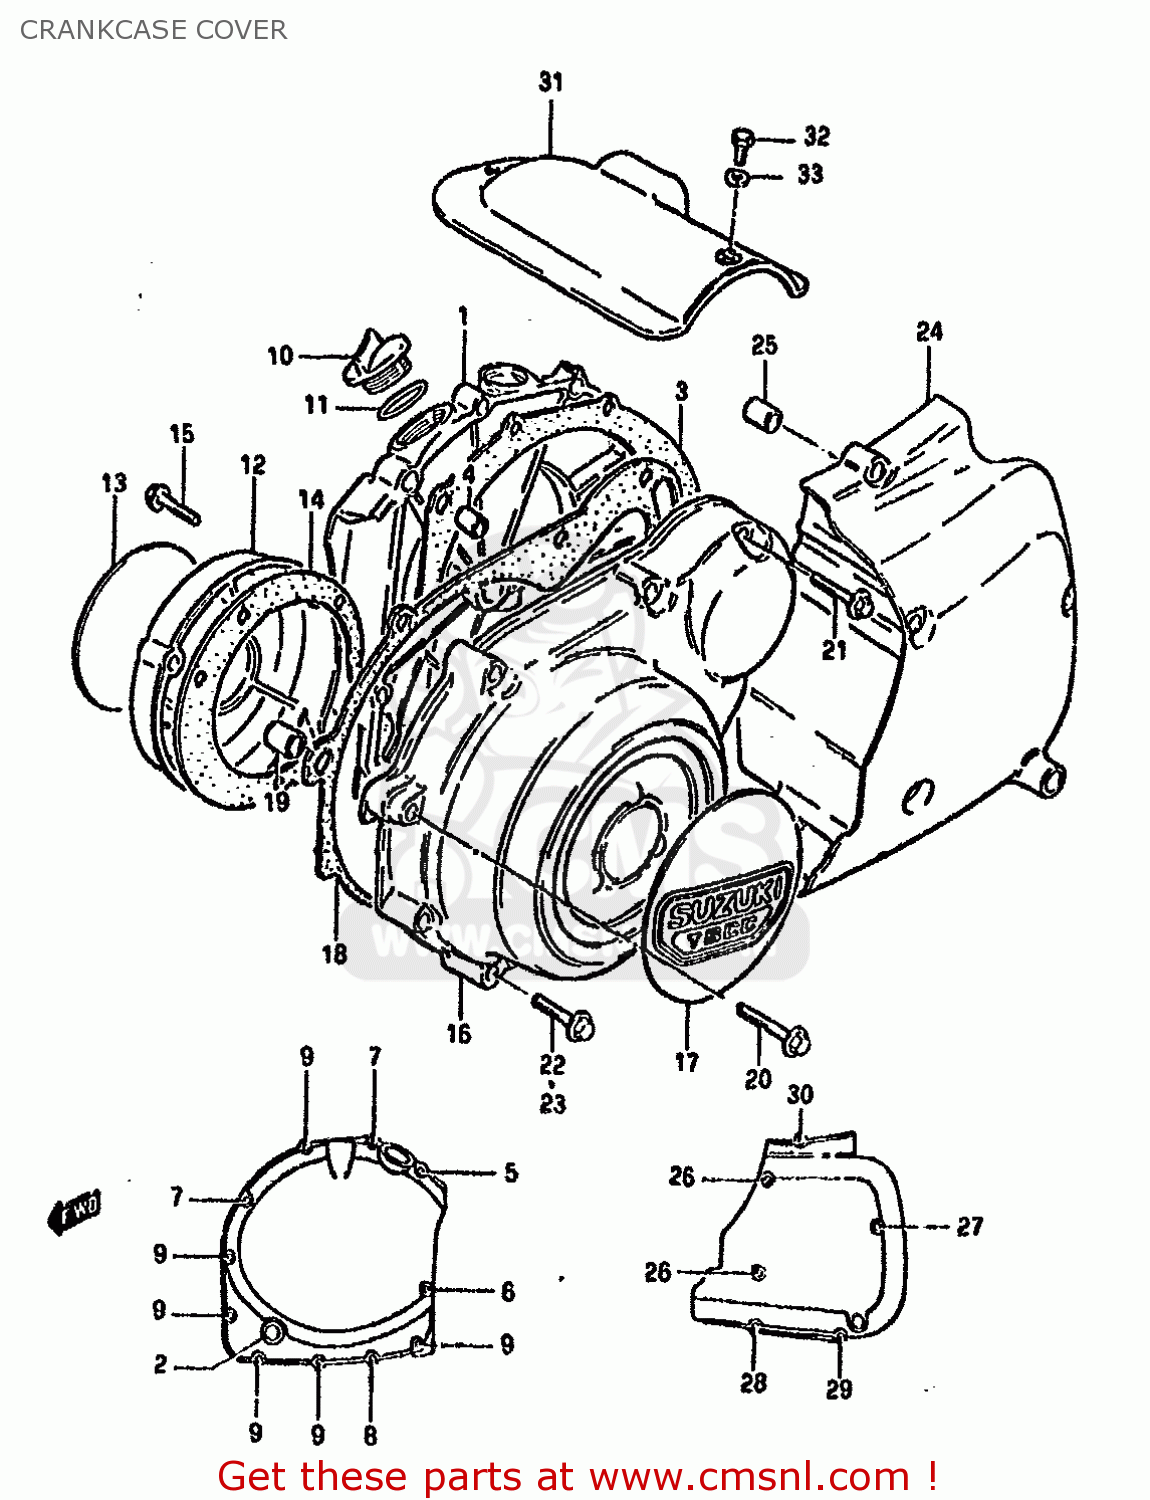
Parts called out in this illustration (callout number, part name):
1	COVER,CLUTCH
2	LENS,OIL LEVEL CHECK
3	GASKET,CLUTCH COVER (MCA)
4	PIN
5	BOLT (6X40)
6	BOLT (6X35)
7	BOLT (6X30)
8	BOLT
9	BOLT (6X20)
10	CAP
11	O RING(D:2.2,ID:32)
12	COVER,CONTACT BREAKER
13	EMBLEM
14	GASKET,CONTACT BREAKER COVER (NAS)
15	BOLT (5*30)
16	COVER,MAGNETO
17	EMBLEM,MAGNETO COVER
18	GASKET,MAGNETO COVER (MCA)
19	PIN
20	BOLT
21	BOLT (6X40)
22	BOLT (6X35)
23	BOLT (6X30)
24	COVER,ENGINE SPROCKET
25	PIN
26	BOLT 6X95
27	BOLT (6X85)
28	BOLT (6X70)
29	BOLT (6X55)
30	BOLT (6X30)
31	COVER,STARTER MOTOR
32	BOLT
33	WASHER
